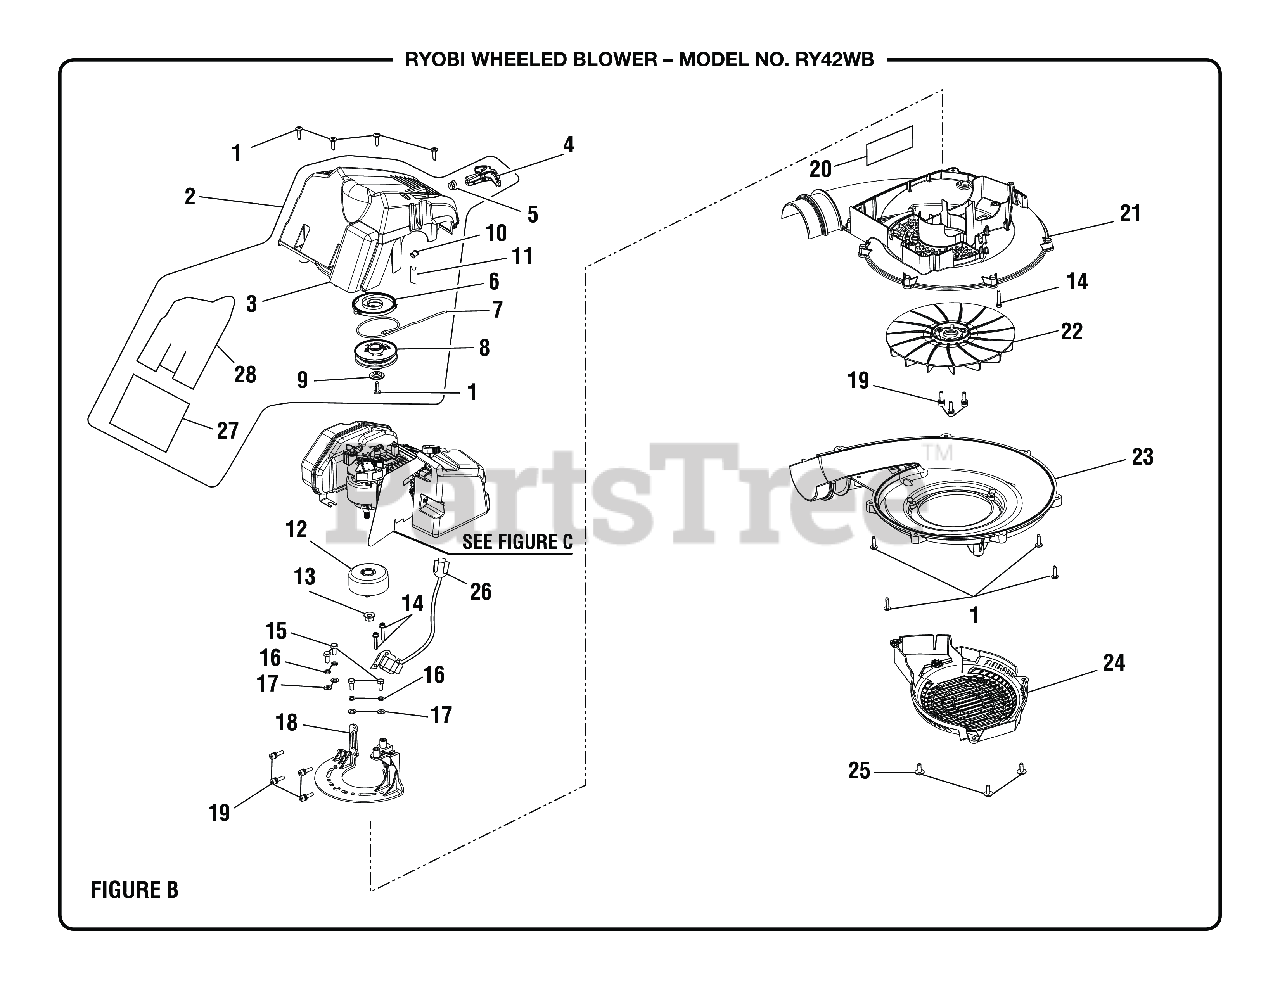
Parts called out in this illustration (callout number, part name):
1	Screw (10-14 x 19 mm, T25 Torx Truss Pan Hd. T.F.)
2	Engine Cover w/Starter Assembly
3	Motor Cover
4	Starter Grip
6	Spring & Container Assembly
7	STARTER ROPE 42 (PKG)
8	Starter Pulley
9	Starter Cap
11	Eyelet Support
13	Lock Nut (M8 x 1.25 in., Left Hand Threads)
14	Screw w/Washer (M5 x 25.4 mm, T25 Pan Hd. T.F.)
15	Screw (M6 x 14 mm, Hex Soc. Hd.)
16	Spring Washer (ID6.4 x 1.6t)
17	Washer (OD12.9 x ID6.6 x 1.2t)
18	Engine Mount
19	Screw w/Washers (M5 x 20 mm, Hex Soc. Hd.)
20	Heat Shield Tape
21	Inner Volute
23	Outer Volute
24	Intake Cover
25	Screw (#10-14 x 3/4 in, T25 Torx Pan Hd. T.F.)
26	Ignition Module (RY08420A)
27	Foil Tape
28	Insulation
